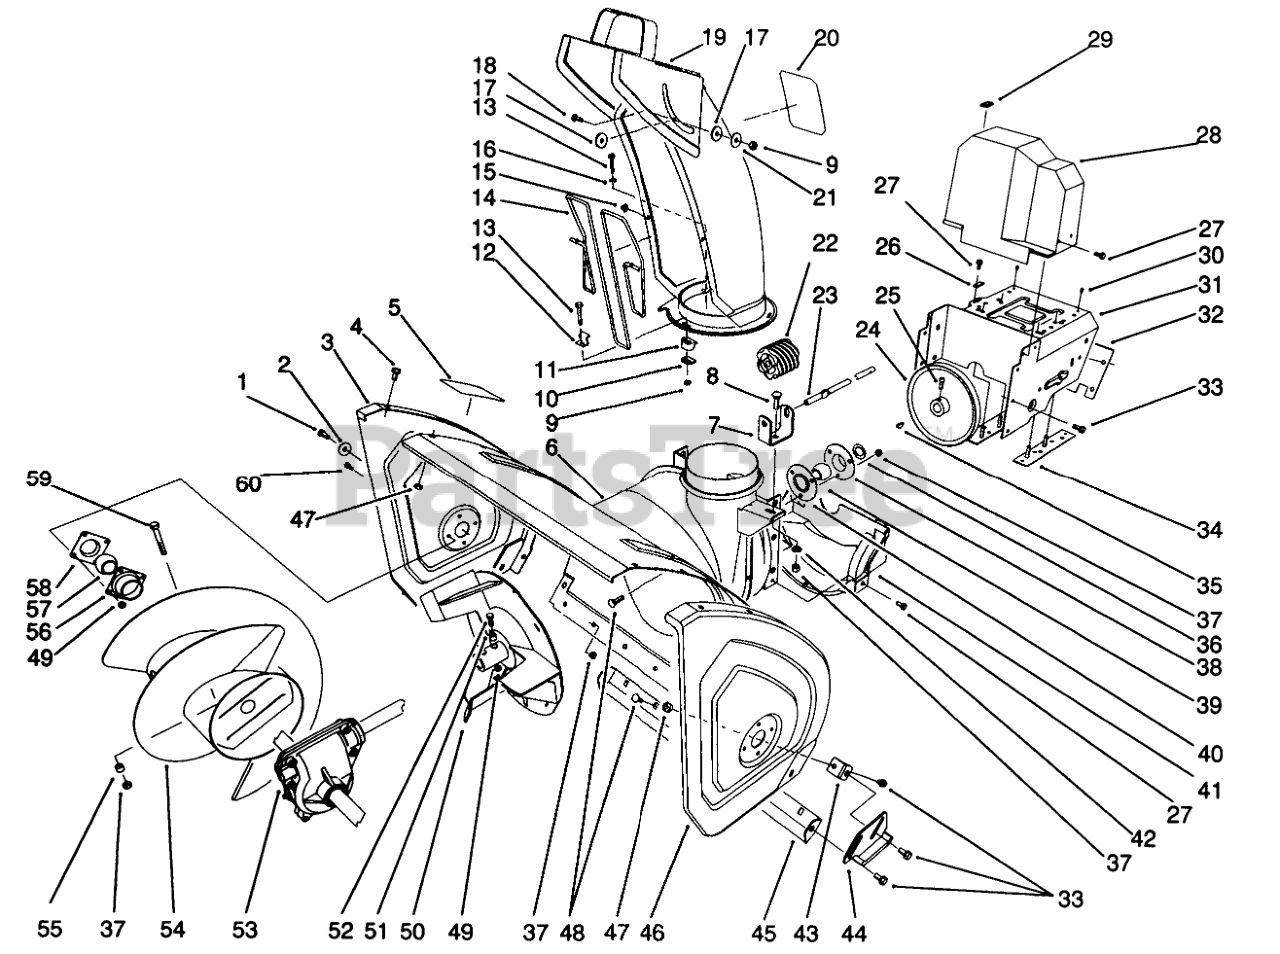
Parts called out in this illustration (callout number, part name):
1	SCREW-HH
2	WASHER
3	PLATE-SIDE, RH
4	SCREW-HHF
5	DECAL-WARNING, AUGER
6	Housing-24 Inch
7	BRACKET-WORM, CHUTE
8	BOLT-CARR
9	NUT-LOCK, NI
10	PLATE-RETAINER, CHUTE
11	RETAINER-CHUTE
12	CLIP-GUARD, CHUTE
13	SCREW-HSH
14	GUARD-CHUTE
15	NUT-PUSH
16	WASHER-FLAT
17	WASHER-PLASTIC
19	Assembly
20	DECAL-DANGER DISCH.
21	WASHER-FLAT
22	GEAR-WORM
23	ROD-CHUTE, LOWER
24	PULLEY-IMPELLER
25	SCREW-SET, SQH
26	RETAINER-CABLE
27	SCREW-HWH
28	COVER-BELT, UPPER
29	COVER-CABLE
30	RIVET-POP
31	Frame-Engine
32	Cover-Frame, Engine
33	SCREW-HHF
34	PLATE ASM FRM LH 6 MITS
35	KEY-WOODRUFF
36	WASHER-THRUST
37	NUT-LOCK, NI
38	Flange-Bearing (Rear)
39	BEARING-BALL
40	Flange-Bearing (Front)
41	Cover-Belt (Lower)
42	WASHER-PLAIN
43	Bracket-Skid
44	SKID WA
45	Blade-Scraper
46	Plate-Side LH
47	NUT-LOCK, NI
48	SCREW-CARR
49	NUT-LOCK, NI
50	Impeller
51	SPACER
52	SCREW-HHF
53	Auger Gearbox ASM
54	Auger-RH
55	SPACER-HUB, AUGER
56	BEARING-FLANGE, FRONT
57	BEARING
58	BEARING-FLANGE, REAR
59	Auger Bolt
60	SCREW-HH
